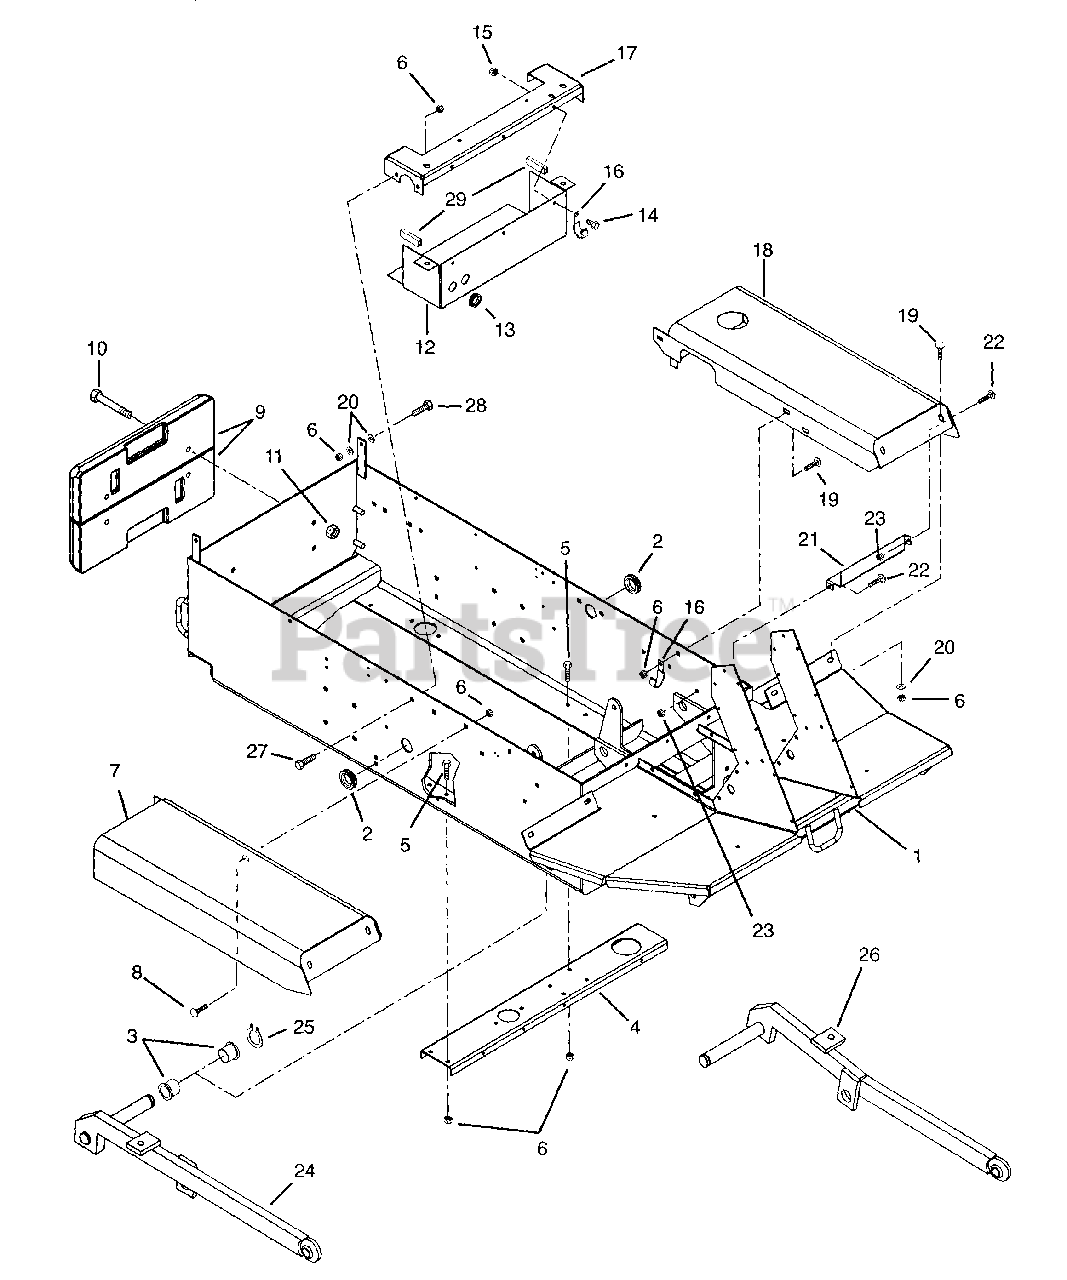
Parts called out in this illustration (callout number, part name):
1	Weldment, Frame
2	Grommet 1.25
3	Bushing, Flange 1.25 x 1.50 x 1.50 Nylon
4	Brace, Frame
5	Bolt-Hex .38-16 x .75 Grade 5
6	Nut-Locking-Center .38-16
7	Weldment, Fender - RH
8	Bolt-Round Head Square Neck .38-16 x 1.00
9	Weight, Rear Frame
10	Bolt-Hex .50-13 x 3.00 Grade 5
10	Bolt-Hex .50-13 x 5.00 Grade 5
11	Nut-Locking-Center .50-13
12	Weldment, Bottom Air Intake
13	Grommet .75 x 1.06 x 1.38
14	Bolt-Hex .31-18 x .50 Grade 5
15	Nut-Locking-Center .31-18
16	J-Clamp
17	Weldment, Seat Cross Support
18	Weldment, L.H. Fender
19	Bolt-Round Head Square Neck .38-16 x .75 Grade 2
20	Washer-Flat-Steel .406 x .812 x .065
21	Bracket, Fuel Tank Front Support
22	Bolt-Round Head Square Neck .25-20 x .75 Grade 5
23	Nut-Locking-Center .25-20
24	Lift Arm Weldment - R.H.
25	Ring-Retaining-External 1.150 x .093
26	Lift Arm Weldment - L.H.
27	Bolt-Hex .38-16 x .75 Grade 5
28	Bolt-Hex .38-16 x 1.00 Grade 5
29	Seal, Trim-Lok
